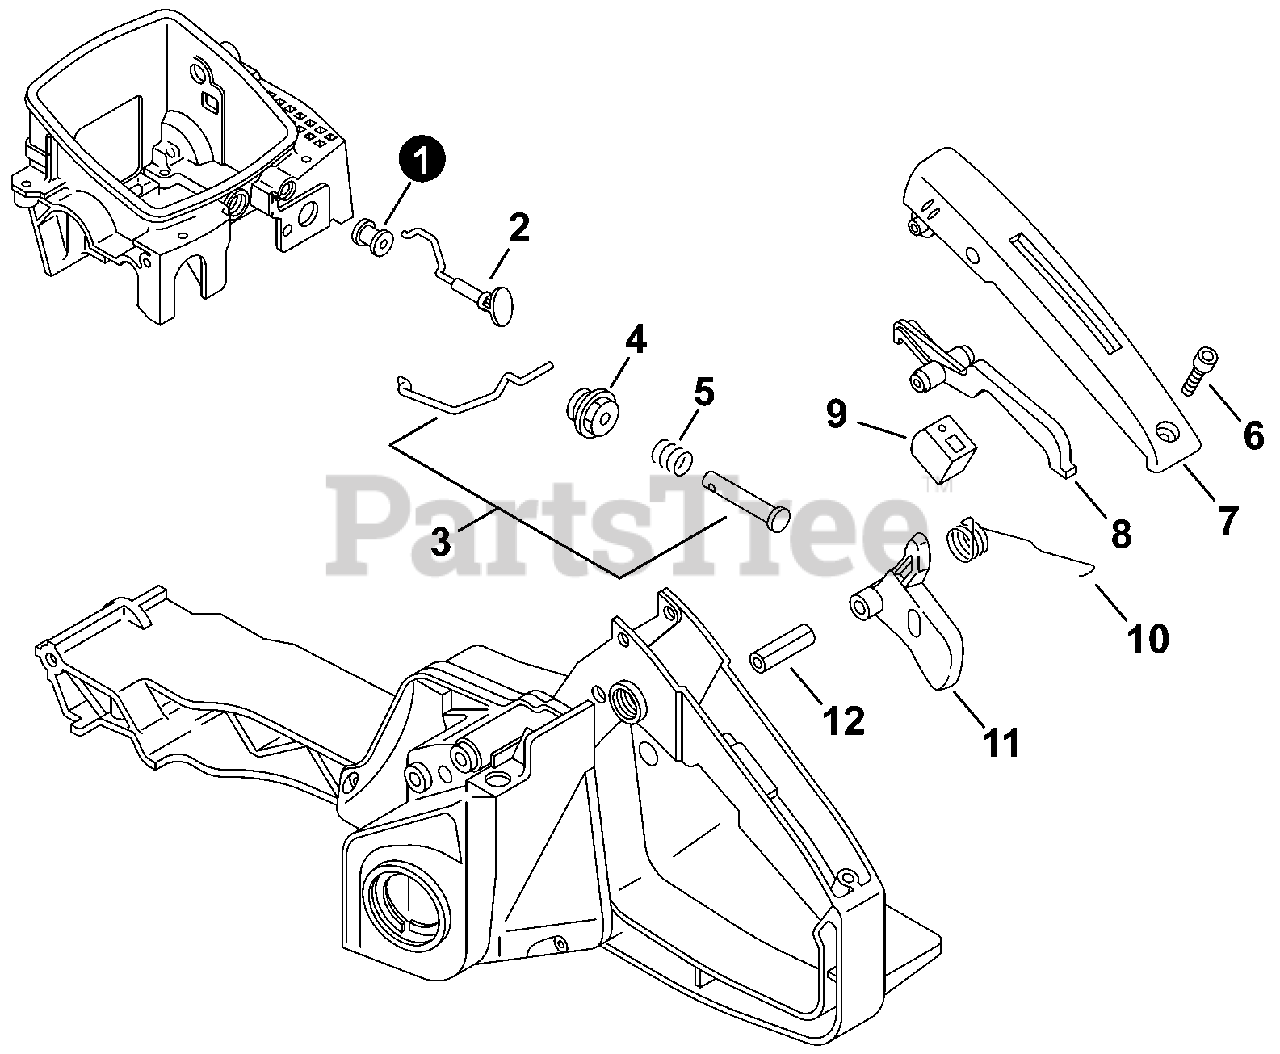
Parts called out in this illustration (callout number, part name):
1	GROMMET, CHOKE
2	ROD, CHOKE - GRAY
2	ROD, CHOKE - ORANGE
3	ROD, THROTTLE
4	GROMMET, THROTTLE ROD
6	BOLT 4x14
7	COVER, HANDLE
8	LEVER, THROTTLE LOCKOUT
9	CUSHION,?THROTTLE
10	SPRING, THROTTLE RETURN
11	TRIGGER, THROTTLE - ORANGE
11	TRIGGER, THROTTLE - BLACK
12	PIN, SPRING ?5x25 MM
